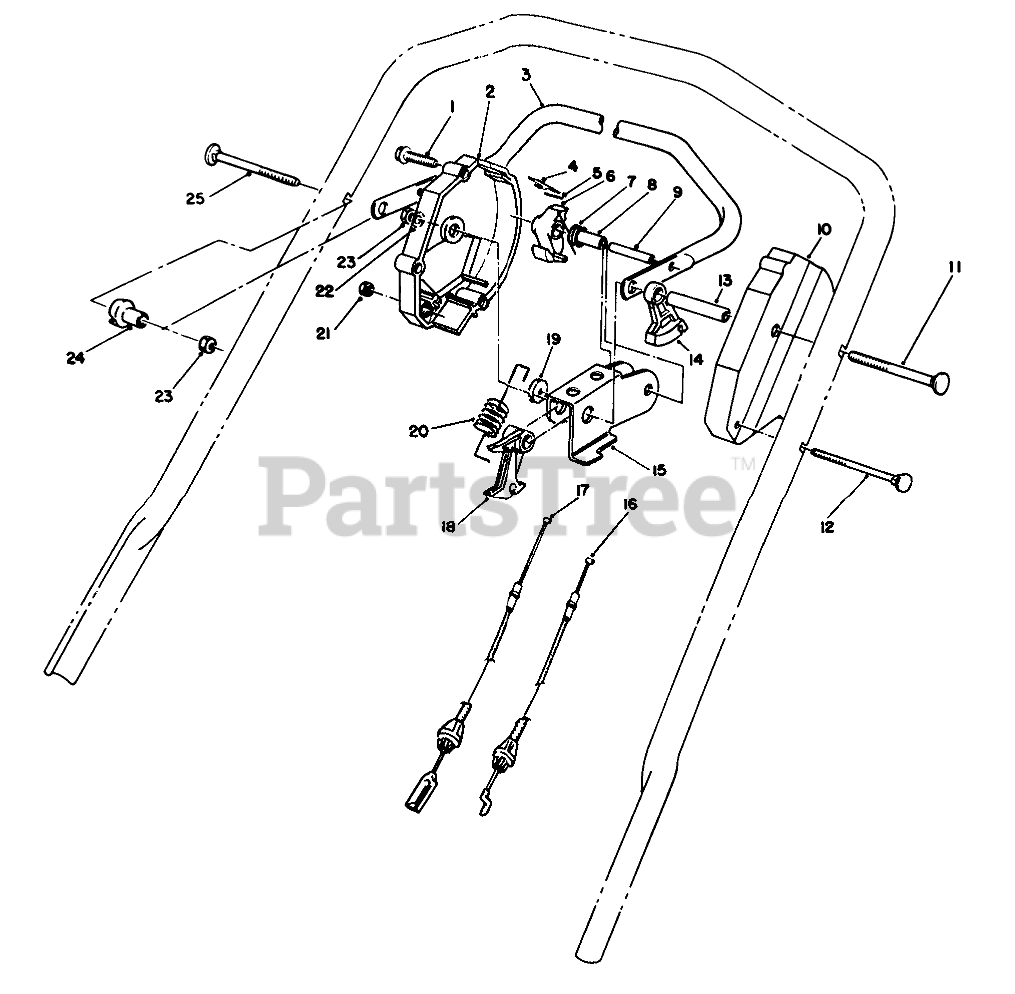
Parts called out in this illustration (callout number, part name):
1	SCREW-HWHTF
2	Housing-Control
3	Bar-Control
4	SPRING-LEAF
5	PIN-INSERT
6	HOOK-CONTROL
7	SPRING-TORSION
8	SPACER
9	PIN-ROLL, SLOTTED
10	HOUSING-CONTROL, LH
11	Screw-Handle
12	HANDLE SCREW
13	TUBING-SPACER
14	LEVER-TRACTION
15	ROCKER
16	TRACTION CABLE
17	BBC CABLE ASSEMBLY
18	LEVER-CABLE
19	WASHER-NYLON
20	SPRING-DETENT
21	NUT-HEX
22	WASHER-PLAIN
23	NUT-LOCK, NI
24	SPACER-SUPPORT
25	SCREW-HANDLE
